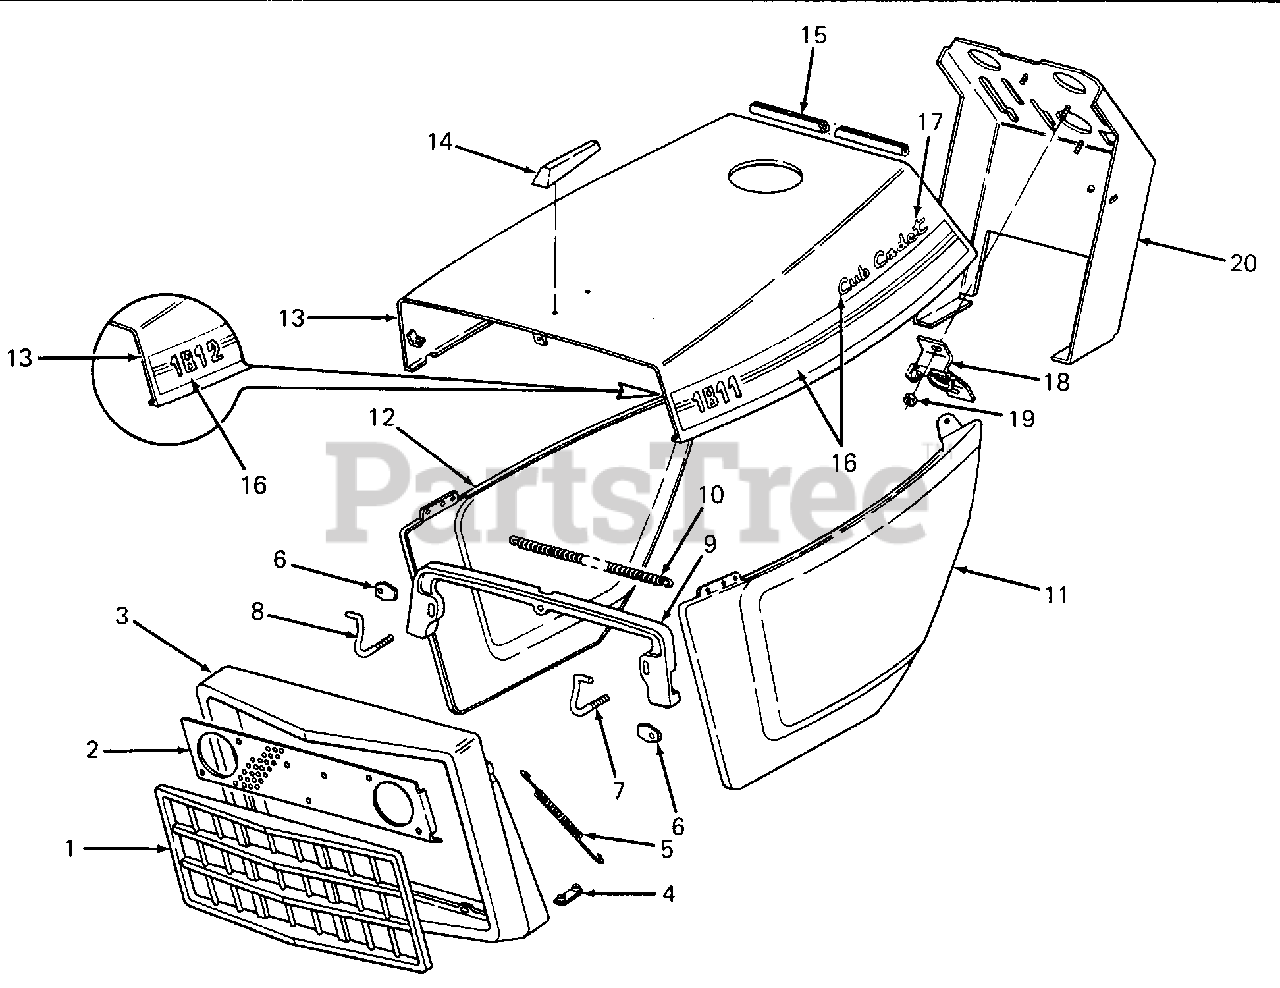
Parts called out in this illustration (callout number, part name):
1	Grille, Insert
4	Retainer, Grille Housing
5	Spring
6	Plate, Hood Hinge
7	Hinge, LH - Hood
8	Hinge, RH - Hood
9	Support, Hood
10	Spring, Side Panel
11	Panel, LH - Side
12	Panel, RH - Side
14	Ornament, Hood
15	Seal, Edge
16	Kit - Hood Label
17	Graphic, Cub Cadet Script w/Adhesive
18	Support, Steering Column
19	Nut, Hex Insert Lock, 1/4-20
